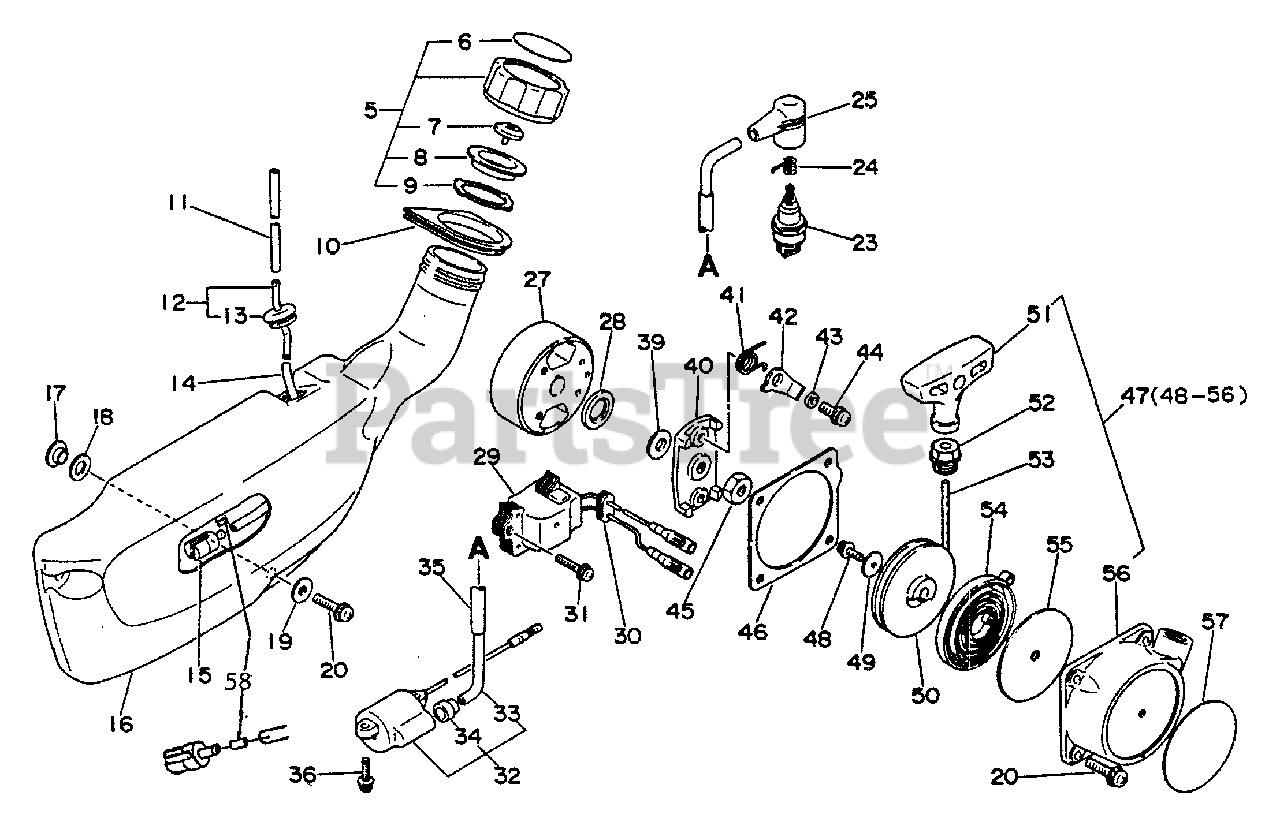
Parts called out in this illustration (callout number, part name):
5	CAP ASSY
6	LABEL - FUEL MIX
7	VENT ASSY
8	HOLDER, CHECK VALVE
9	GASKET, FUEL CAP
10	BUSHING
11	PIPE, FUEL
12	CONNECTOR
14	PIPE, FUEL
15	FILTER, FUEL
16	TANK, FUEL
19	WASHER 5.5×16×0.8
20	SCREW 5×20
23	SPARK PLUG - CJ-7Y
24	TERMINAL, SPARK PLUG
25	CAP, SPARK PLUG
27	FLYWHEEL
29	COIL, IGNITION
31	SCREW 4×20
32	COIL, IGNITION
33	CORD, HIGH TENSION
36	SCREW 4×14
39	WASHER 8.5×16×1.2
40	PAWL CATCHER
42	RATCHET
43	SPACER 5.2×8×2.1
44	SCREW 5×10
46	GASKET, STARTER
47	STARTER ASSY
48	SCREW 4×10
49	WASHER 4.1×15.5×1T
50	REEL, ROPE
51	GRIP, STARTER
52	GUIDE, ROPE
53	ROPE, STARTER 3.0×850
54	SPRING, RECOIL
56	CASE, STARTER
57	LABEL - ECHO
58	VALVE, CHECK
